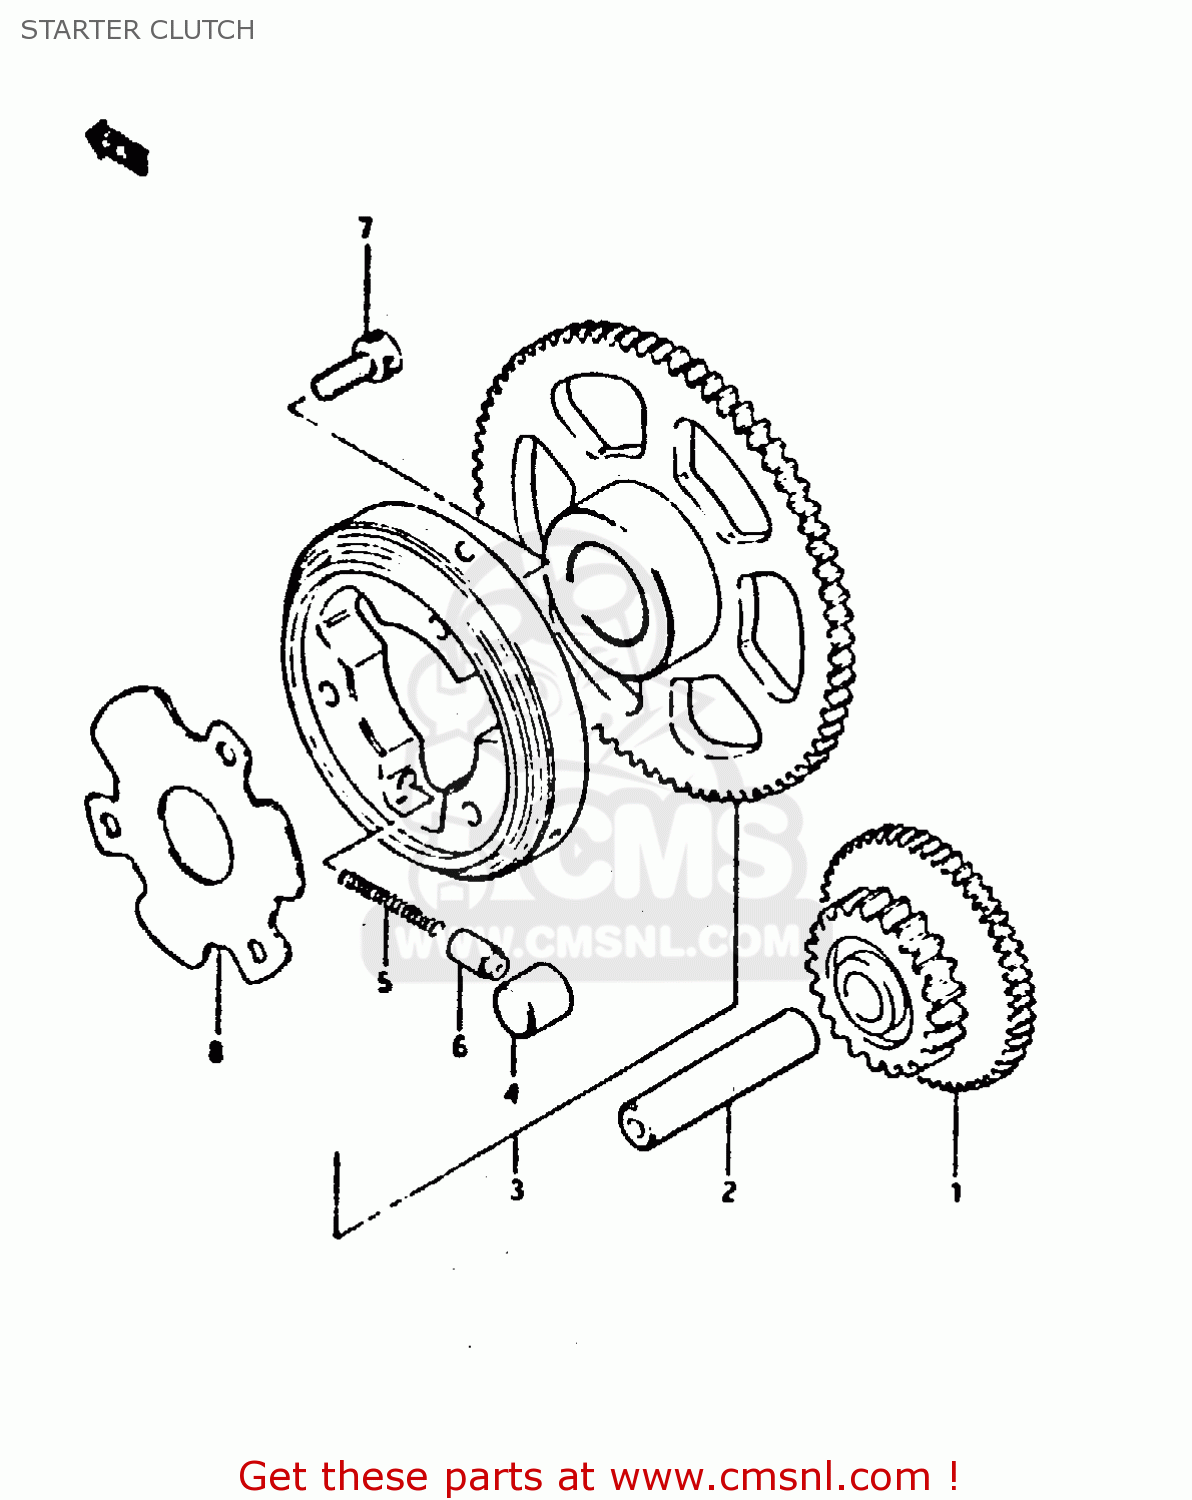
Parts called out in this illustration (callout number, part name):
1	GEAR,STARTER IDLE
2	PIN(7.4X13X56)
3	CLUTCH SET,STARTER
4	ROLLER(15X13)
5	SPRING
6	PIECE,PUSH
7	BOLT
8	SHIM,STARTER CLUTCH HUB
